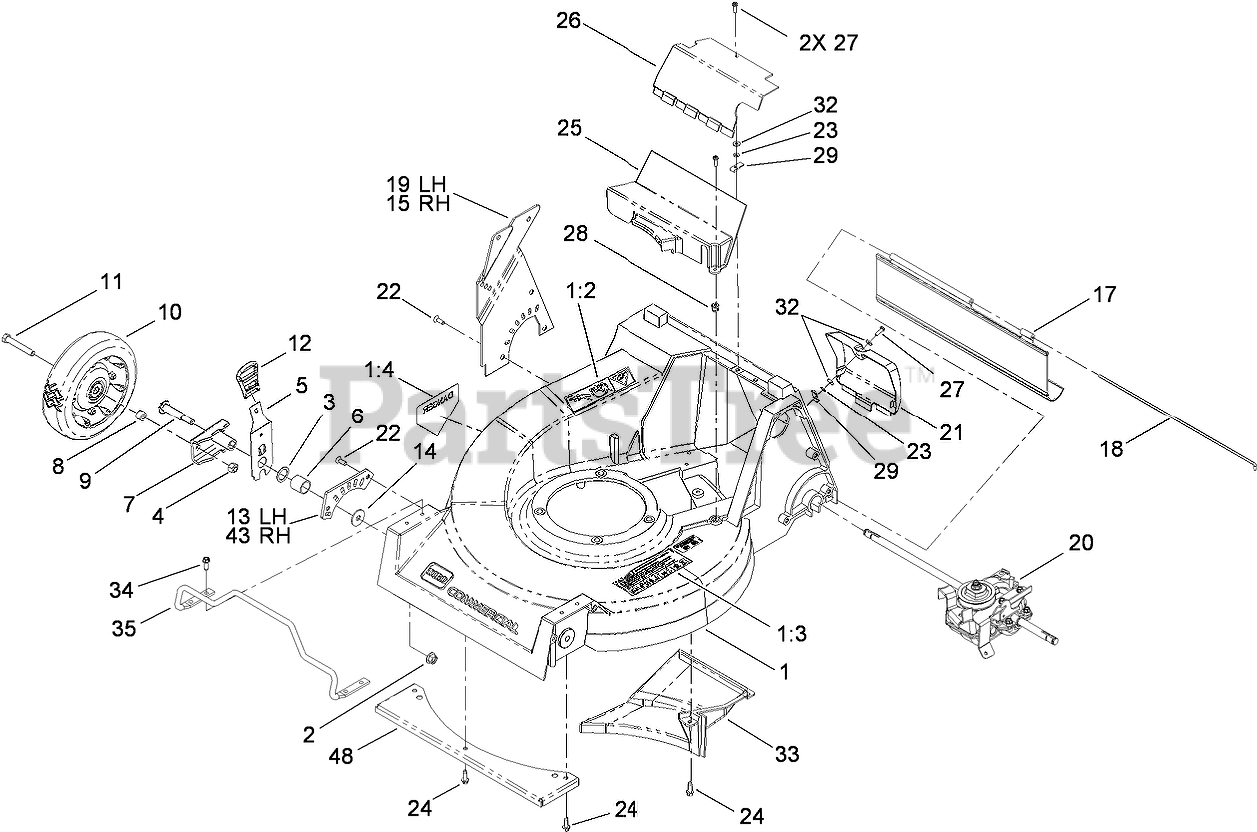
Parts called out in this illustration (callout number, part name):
1	DECK ASM
1:2	DECAL-DANGER
1:3	DECAL-DANGER
1:4	DECAL-DANGER
2	NUT-LOCK
3	WASHER
4	NUT-LOCK, CONE
5	FRONT SPRING ARM ASM
6	SPACER-BEARING
7	ARM-PIVOT, FRONT
8	SPACER-WHEEL
9	SCREW-SHOULDER
10	Wheel and Tire ASM
11	SCREW-HH
12	KNOB-HOC
13	PLATE-FRONT HOC, LH
14	WASHER
15	PLATE-REAR HOC, RH
17	SHEILD-TRAILING
18	ROD-SHIELD
19	PLATE-REAR HOC, LH
20	GEAR CASE ASM
21	DOOR-ACCESS, REAR
22	SCREW-HH
23	NUT-PUSH
24	SCREW-HWH
25	COVER-BELT, LOWER
26	COVER-BELT, UPPER
28	NUT-CLIP
29	NUT-TYPE J
32	WASHER-FLAT
33	BAFFLE-CHUTE, FLOOR
34	SCREW-HWHTF
35	GUARD-ENGINE
43	PLATE-FRONT HOC, RH
48	SHIELD-FRONT, HI-VAC
